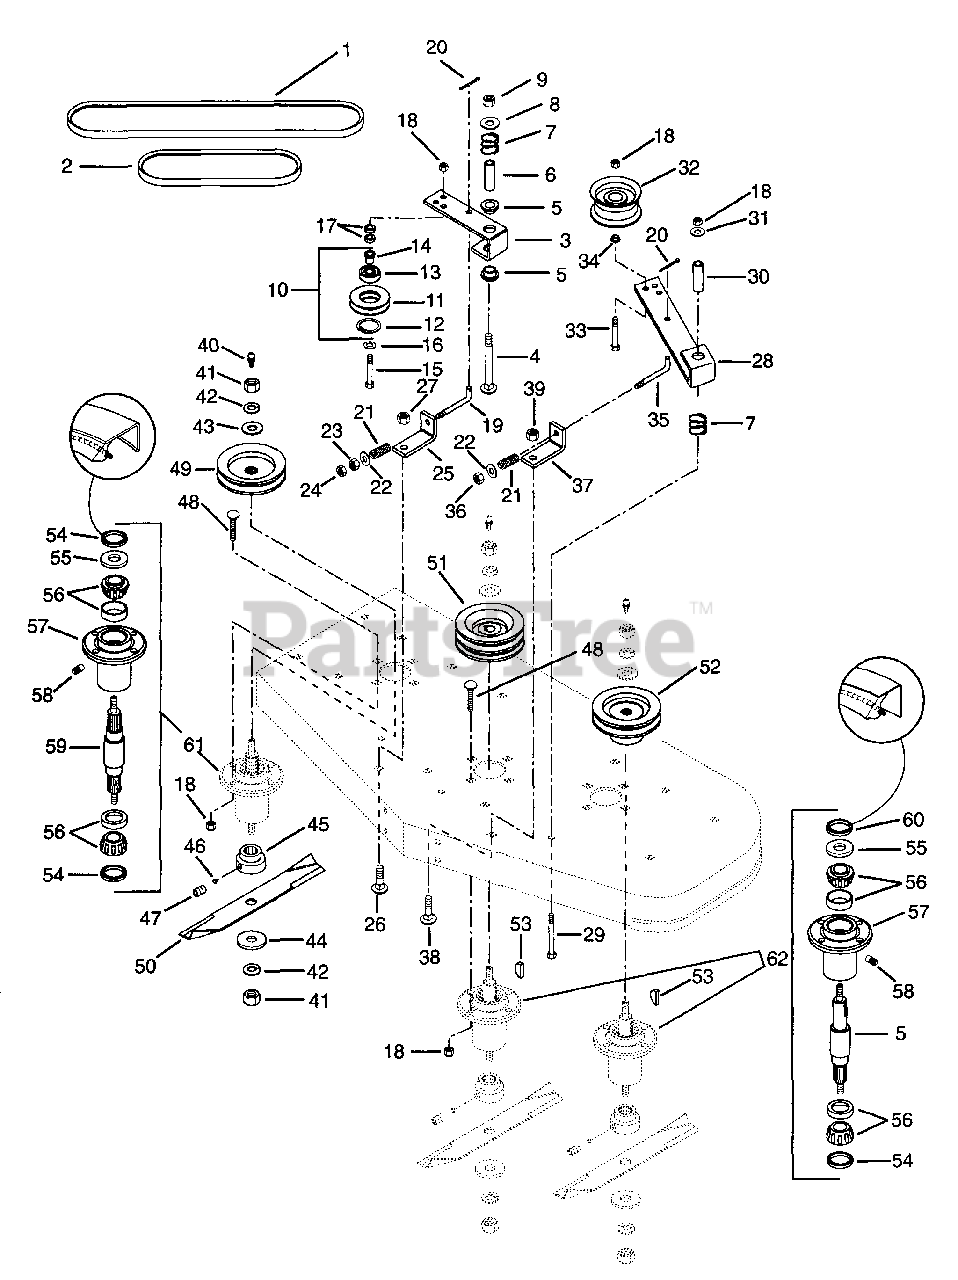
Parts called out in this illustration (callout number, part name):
1	V-Belt A-Section 50.25 x .561/.031
2	V-Belt A-Section 18.05 x .495
3	Arm, Idler Pivot
4	Bolt Round Head Square Neck .50-16 x 3.50
5	Bushing-Flange .762 x 1.0 x .580 x 1.48
6	Spacer .560 x .750 x 2.437
7	Spring-Compression .085 x .80 x 1.00
8	Washer-Flat-Steel .500 x 1.250 x .083
9	Nut-Locking .50-13
10	Assembly, Idler Sheave
11	Sheave, Idler
12	Ring-Retaining-Internal 2.054 x .062
13	Bearing-Ball 1.85 x .787 x .55
14	Bushing-Flange .786 x 1.0 x .79
15	Bolt-Hex .38-16 x 2.00 Grade 5
16	Washer-Flat-Steel .375 x 1.125 x .065
17	Bushing .406 x .750 x .188
18	Nut-Locking-Nylon .375-16 Grade 2
19	Rod, Idler
20	Pin-Cotter .09 x .75
21	Spring-Compression .125 x .78 x 1.00
22	Washer-Flat-Steel .281 x .625 x .065
23	Nut-Hex .375-16 Grade 2
24	Nut-Jam .375-16
25	Bracket, Belt Tensioner
26	Bolt-Round Head Square Neck .50-13 x 1.50
27	Nut-Locking-Nylon .50-13 Grade 5
28	Weldment, Ground Drive Idler
29	Bolt-Hex .38-16 x 3.50 Grade 5
30	Bushing, Steel .437 x .750 x 2.44
31	Washer-Flat-Steel .438 x 1.0 x .083
32	Idler-Flat 4-.687 x .38
33	Bolt-Hex .38-16 x 2.25 Grade 5
34	Bushing-Flange .406 x .88 x .270 x .140
35	Rod, Idler 50 In. Mower
36	Nut-Hex .375-24 Grade 2
37	Bracket
38	Bolt-Round Head Square Neck .31-18 x 1.0
39	Nut-Locking-Nylon .312-18 Grade 2
40	Fitting-Lube 1/8
41	Nut-Hex .625-11 Grade 2
42	Washer-Locking .625 x .156
43	Washer-Flat-Steel .97 x 1.865 x .063
44	Washer
47	Screw-Set .25-20 x .25
48	Bolt, Round Head Square Neck .38-16 x 1.375
49	Sheave
50	Blade, 50 Inch Mower
51	Sheave
52	Sheave
53	Key-Woodruff .25 x 1
54	Seal 1.987 x 1.375 x .313
55	Washer-Flat-Steel 1.007 x 1.542 x .062
56	Assembly, Bearing Cup & Cone
57	Housing, Bearing
58	Relief Fitting - Grease
59	Shaft, Spindle
60	Seal 1.987 x 1.500 x .313
61	Service Kit
62	Service Kit
